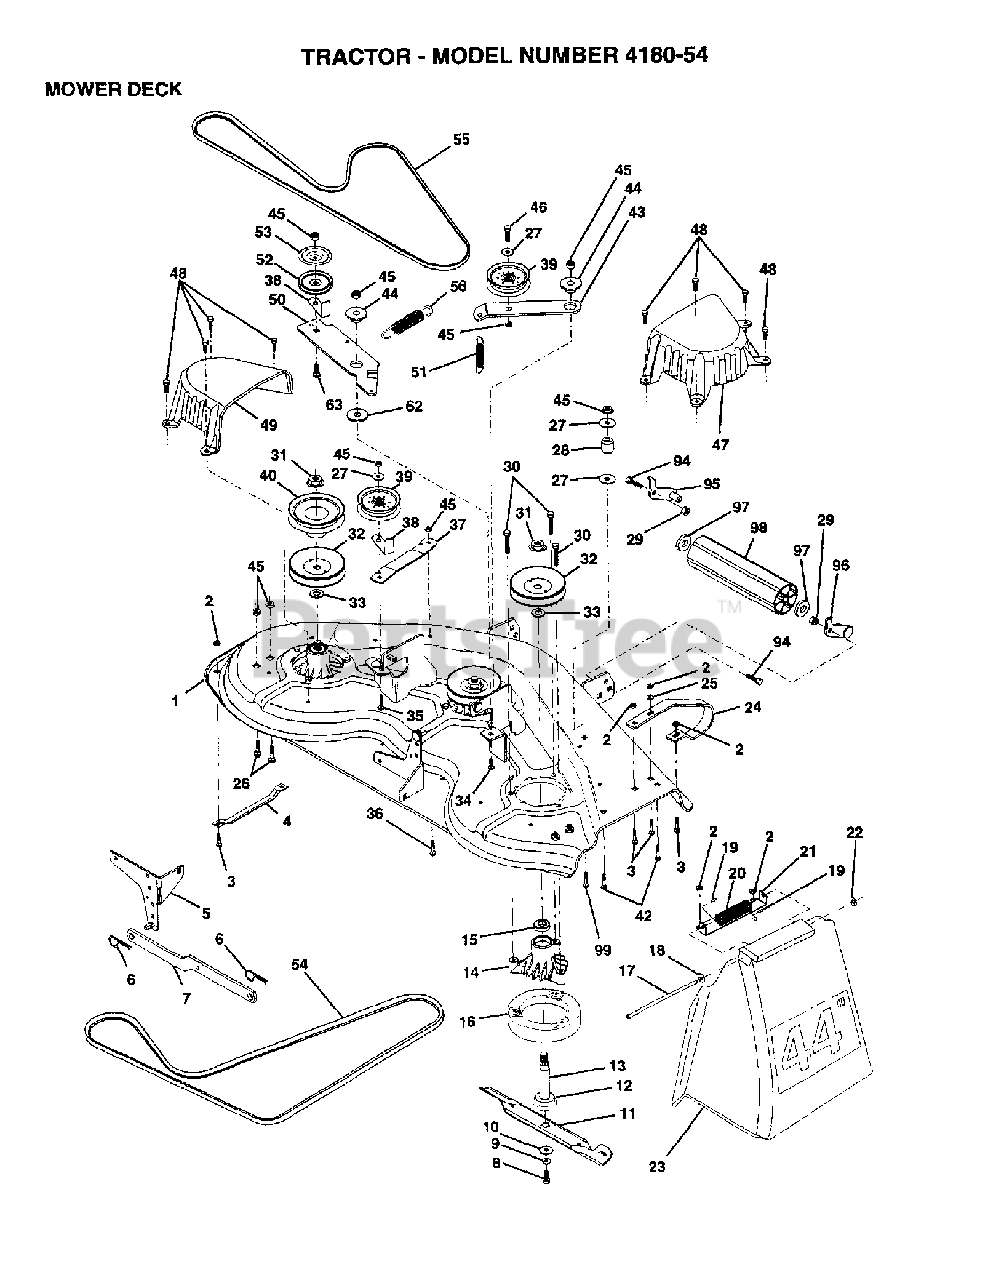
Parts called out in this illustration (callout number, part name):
2	LOCKNUT
3	BOLT.5/16-18.
4	RUNNER LH
5	BRACKET SWAY BAR
6	RETAINER SPRING
8	BLADE BOLT
10	WASHER.BLADE
11	44" BLADE-HI PERFORMANCE
12	BEARING.BALL.#6204.(MANDREL)
13	SHAFT.ASM.W/BEARING
14	HOUSING.MANDREL
17	ROD-HINGE T
18	WASHER
19	CAP-SLEEVE LT
20	DEFLECTOR SPRG T
21	BRACKET, DEFLECTOR
22	NUT PUSH M
23	DEFLECTOR SHIELD
24	RUNNER-RH YTV
25	WASHER M
28	IDLER SPRING SPACER
29	NUT
30	Hex Washer Head Bolt, .313-18 X 1.19
33	WASHER
35	BOLT
37	STIFFENER ARM
39	IDLER-FLAT GT
40	PULLEY.DRIVEN.44"
42	BOLT
43	ARM.IDLER.SEC.44"
45	LOCKNUT
46	BOLT
47	COVER MANDRELL
48	SCREW.1/4-20X5/8
49	COVER.MANDREL.LH.44"
50	ARM.IDLER.PRIMARY
51	SPRING.SEC.44"VEN
52	PULLEY IDLER
53	SHIELD IDLER
55	BELT
63	BOLT.3/8-16X1.50
94	BOLT
95	Roller Bracket Assembly, LH
98	MANUAL, OPERATOR
99	BOLT
